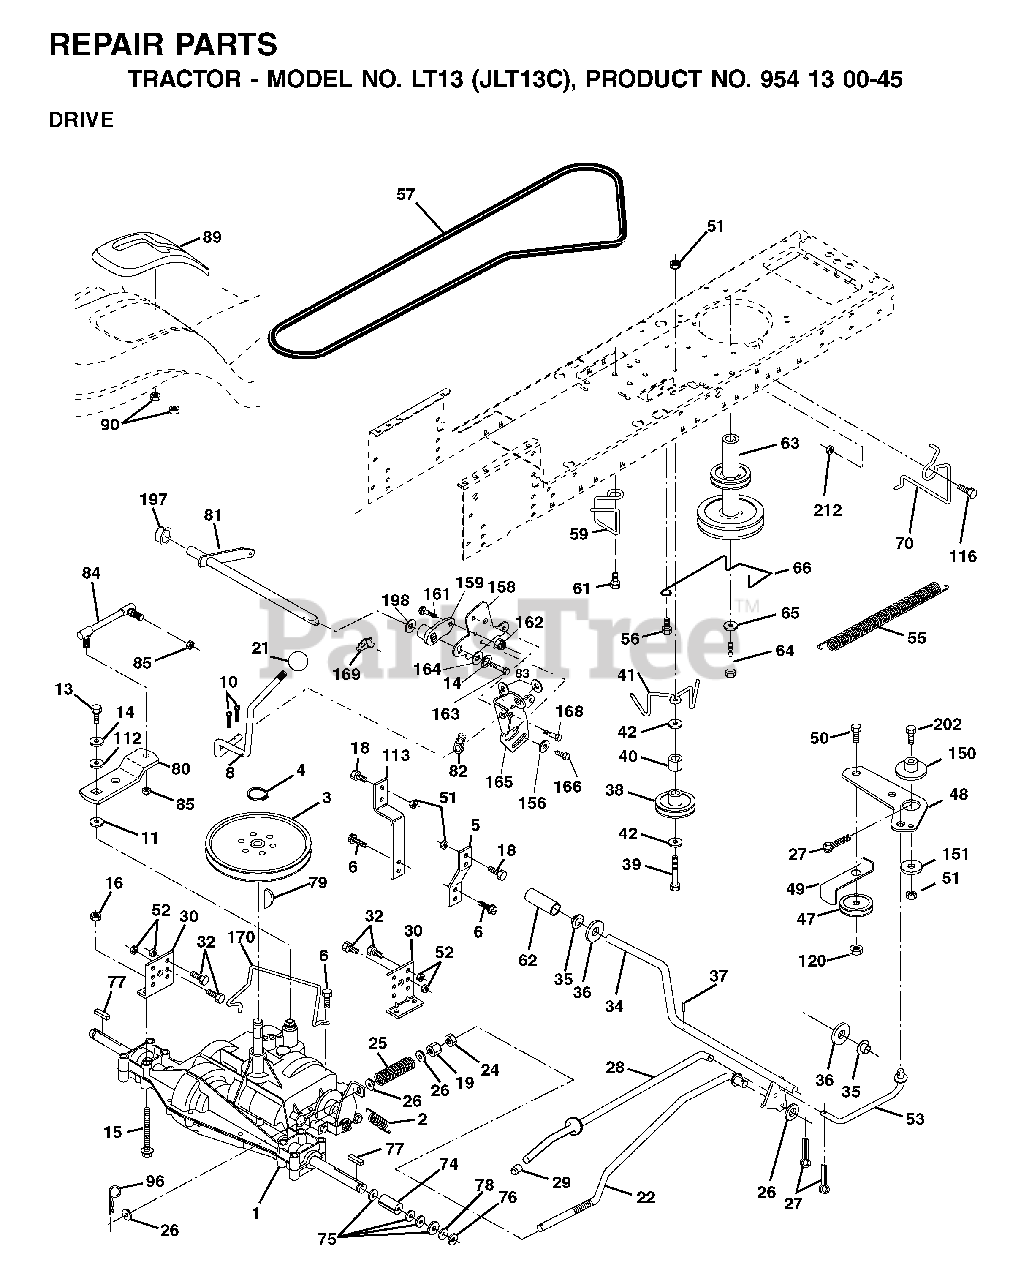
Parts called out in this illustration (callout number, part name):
2	SPRING,BRAKE RETURN
3	PULLEY TRANS
4	RETAINING RING LT
5	STRAP TORQUE
6	SCREW 5/16"
8	ROD SHIFT FENDER ADJUST STLT
10	PIN COTTER
11	WASH-SHFT PLT LT
13	BOLT 1/4-28X3/4
14	LOCKWASHER
16	NUT.71038.31-18.HEX.NYLOCK
19	NUT
21	KNOB.DUCKHEAD.1/2
22	ROD BRAKE
24	NUT
25	SPRING ROD LT
27	COTTER PIN
28	ROD, PARKING BRAKE
29	PLUNGER CAP
30	BRKT, MOUNT TRNSAXLE
32	BOLT
34	SHAFT, FOOT PEDAL
35	BEARING.NYLON
36	WASHER LT
37	DRIVE PIN
38	PULLEY.FLAT
39	BOLT
40	SPACER, SPLIT
41	KEEPER, BELT IDLER
42	WASHER
47	IDLER PULLEY
48	BELLCRANK, CLUTCH
49	RETAIN BELT
50	BOLT
51	LOCKNUT
52	LOCKNUT
53	LINK, CLUTCH LT
55	SPRING, RETURN LT
57	V-BELT
59	KEEPER, BELT CENTER
61	SCREW 3/8-16X3/4
62	PEDAL COVER T
63	ENGINE PULLEY
64	BOLT
65	LOCKWASHER
66	KEEPER BELT ENGINE
70	KEEPER BELT ENG
74	SPACER AXLE
76	E-RING LT
77	SQUARE KEY
80	ARM SHIFT
82	SHIFT SPRING
83	WASHER
85	NUT LOCK CENTER 1/4 -28 FNTHD
89	CONSOLE.SHIFT.STLT.6SP.BLACK
96	RETAINER M
112	WASHER LT
113	STRAP TORQUE LH LT
116	BOLT D
120	NUT LOCK FLG 3/8-16 UNC
150	SPACER, RETAINER
151	WASHER 12/32X2X10GA
156	WASHER.SRRTD.5/16
158	BRACKET
159	HUB
161	BOLT
162	NUT.CROWNLOCK.1/4
165	RP BRACKET
168	BOLT.SHOULDER.5/16-18X
169	PLATE.FASTENING.CROSS.SHAFT
170	KEEPER BELT T/A
197	NYLINER SNAP 5/8" ID
198	WASHER.NYL.7/8IDX.105"HYD CR
202	BOLT
212	NUT
